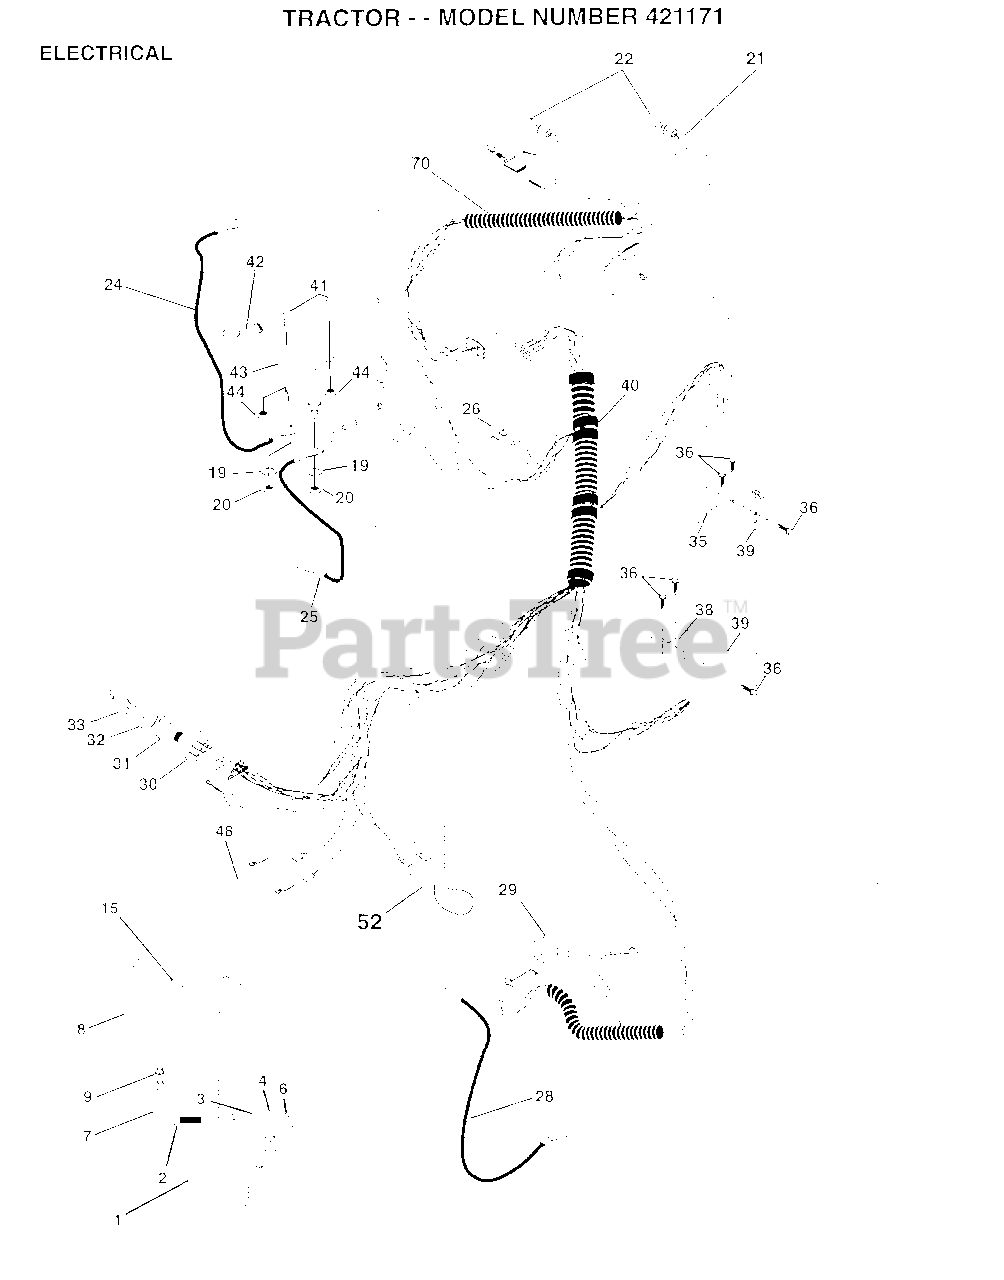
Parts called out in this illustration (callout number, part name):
1	Battery12 Volt 25 Amp
2	BOLT LT
3	WASHER
4	LOCKWASHER
7	TUBE T
9	HOSE CLAMP T
15	FASTNER.SNAP-IN
20	NUT
21	"HARNESS,LIGHT SOC"
22	HEADLAMP BULB
24	CABLE-BATTERY T
25	CABLE.BTRY.6GA.RD
26	FUSE HYT
28	CABLE T
29	SWITCH SEAT
30	SWITCH IGN 4POS
31	NUT IGNITION
32	COVER KEY SWITCH
33	KEY
35	BRACKET LT
36	SCREW
38	BRACKET SWITCH IN
39	SWITCH INTERLOCKT
40	HARNESS.IGNITION
41	BOLT HXHD FIN
44	NUT HXKEP 1/4X20
48	ADAPTER AMMETER
52	PROTECTION LOOP
70	HARNESS.ENG.LT.
